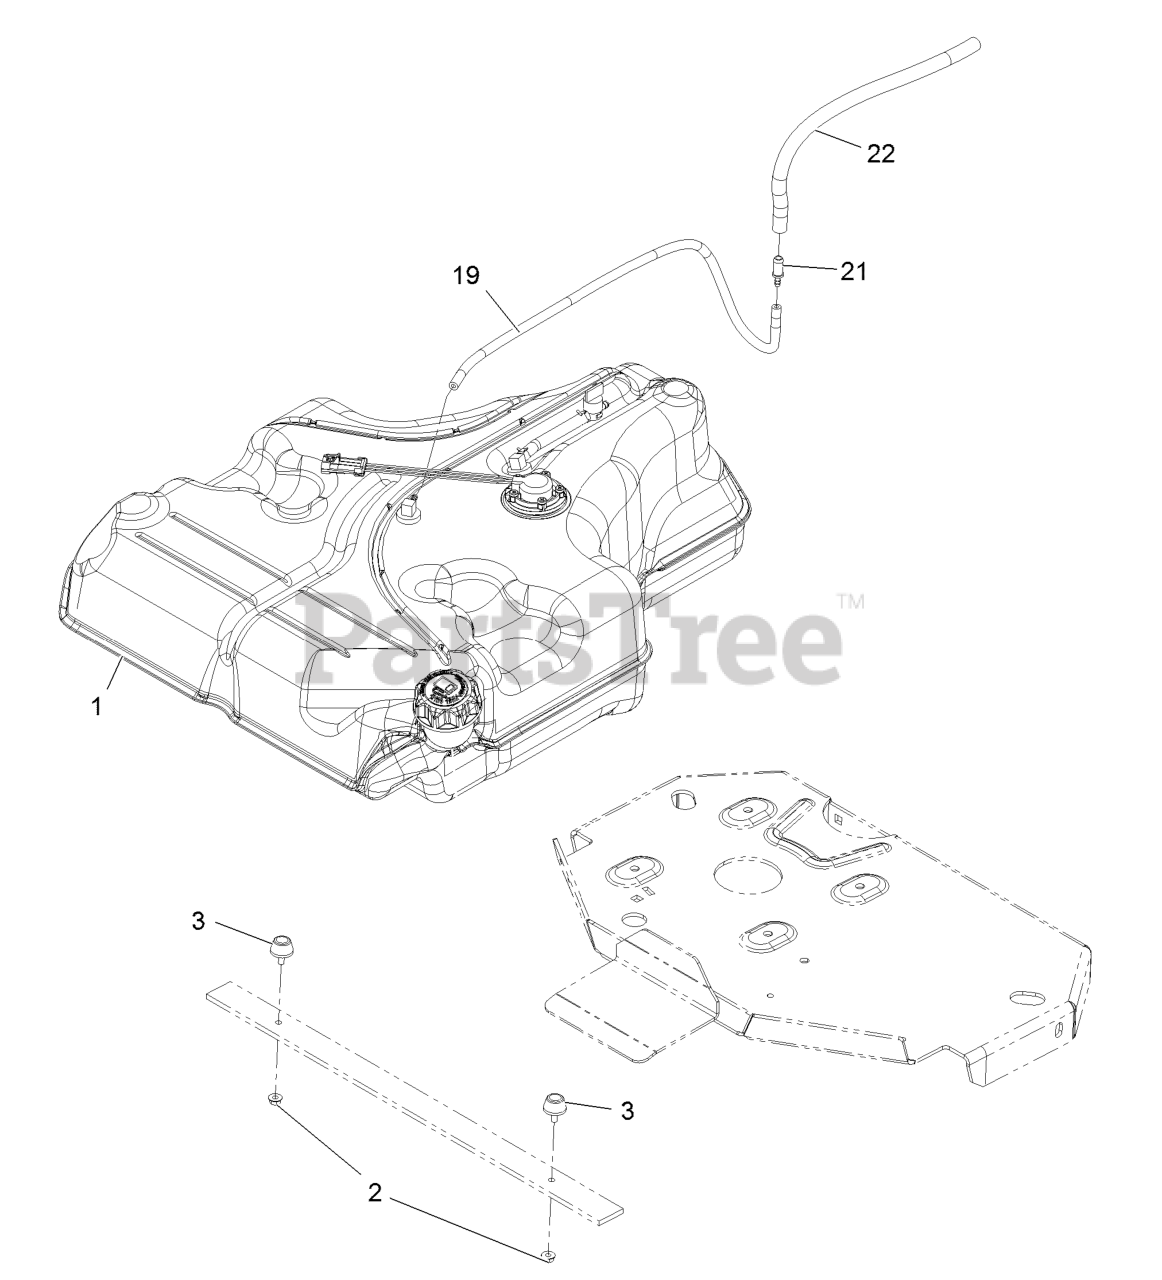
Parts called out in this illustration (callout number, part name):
2	NUT-JAM
19	HOSE-FUEL
21	FITTING-STRAIGHT
22	HOSE-FUEL
